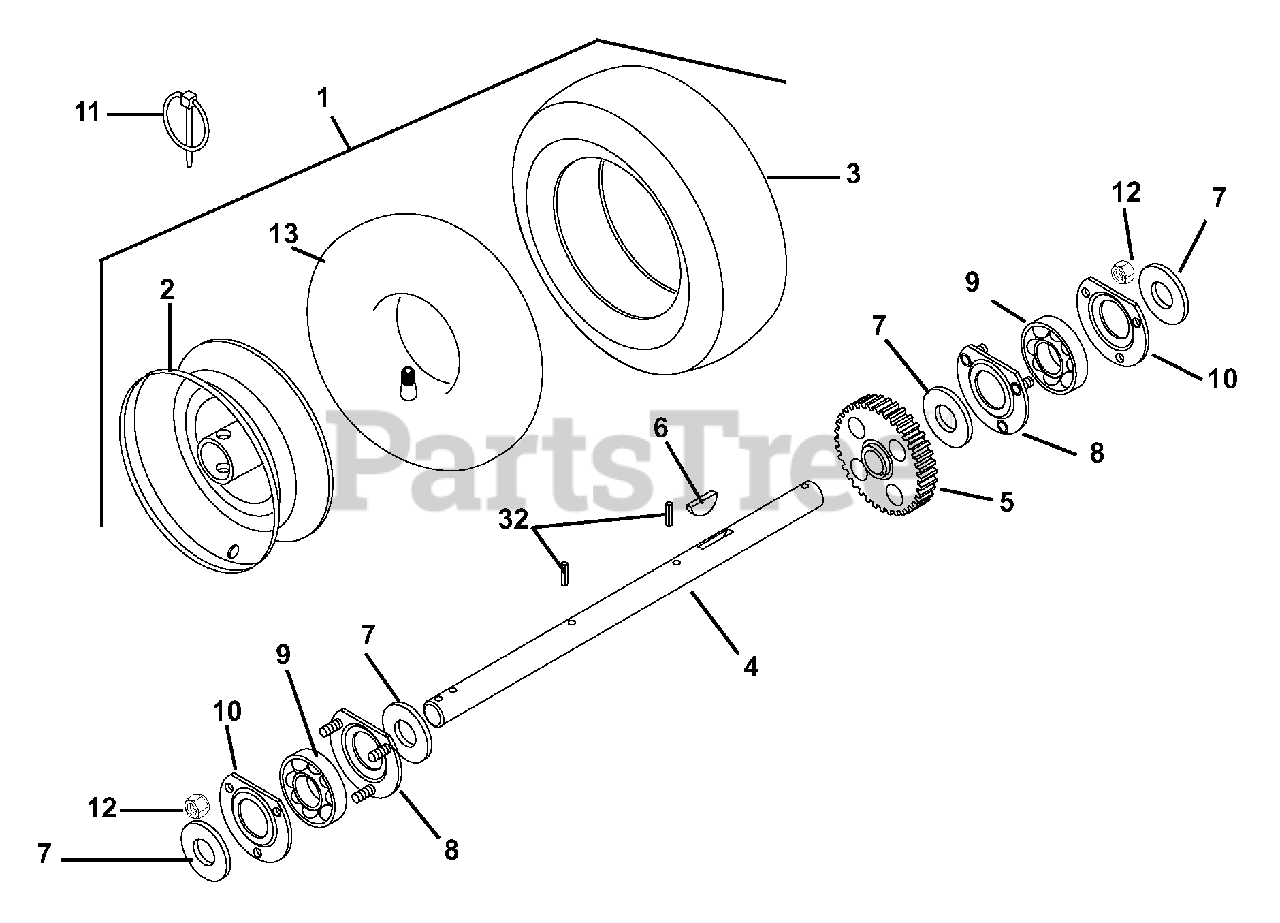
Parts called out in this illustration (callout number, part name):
1	TIRE/WHEEL ASSEMBLY 16X4.80-8
1	TIRE/WHEEL ASSEMBLY 16X6.5-8
2	WHEEL, 6.50-8.00
2	WHEEL, 4.5-8
3	TIRE 4.80-8 NHS
3	TIRE 16X6.50-8 SNO-HOG TREAD
4	SHAFT, AXLE
5	GEAR, SPUR-FELLOWS 35T .875 ID
6	KEY-WDRF .25X.750X.313 SAE91
7	WSHR-FL-STL .880X1.250X.062YWZ
8	BEARING FLANGE
9	BRG-BALL .876 X 1.750 X .50
10	BEARING FLANGE
11	PIN-LOK .31X1.75
12	@NUT-LK-CTR .25-20 YWZC
13	TUBE
32	PIN-ROLL .188X1.50
